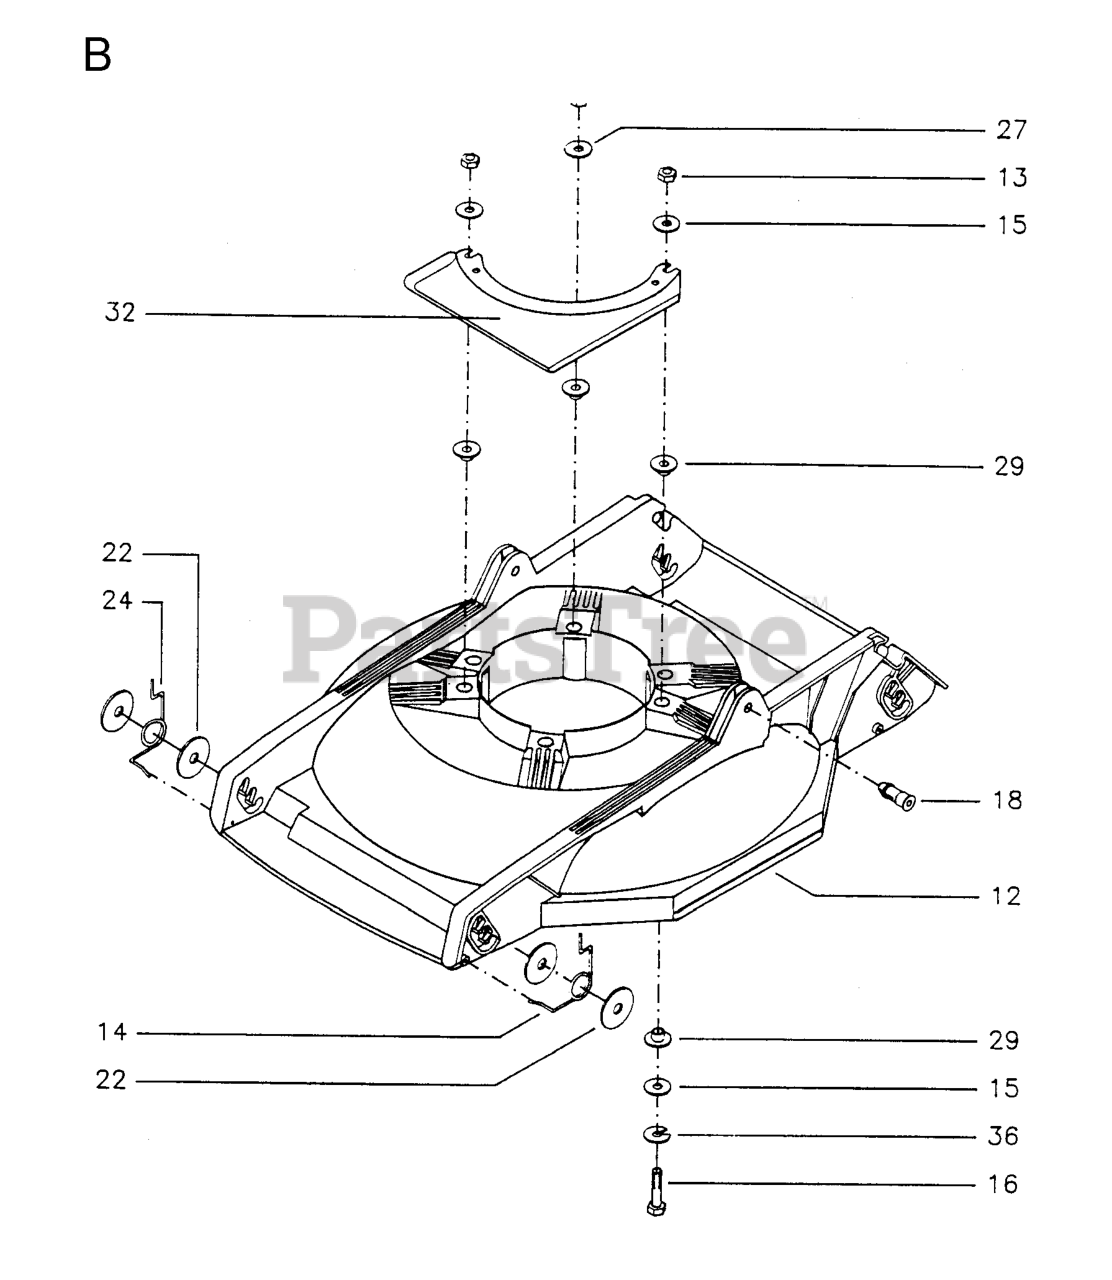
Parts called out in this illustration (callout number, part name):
13	LOCKNUT M8
29	FLANGE BRG.
36	SPRING WASHER
